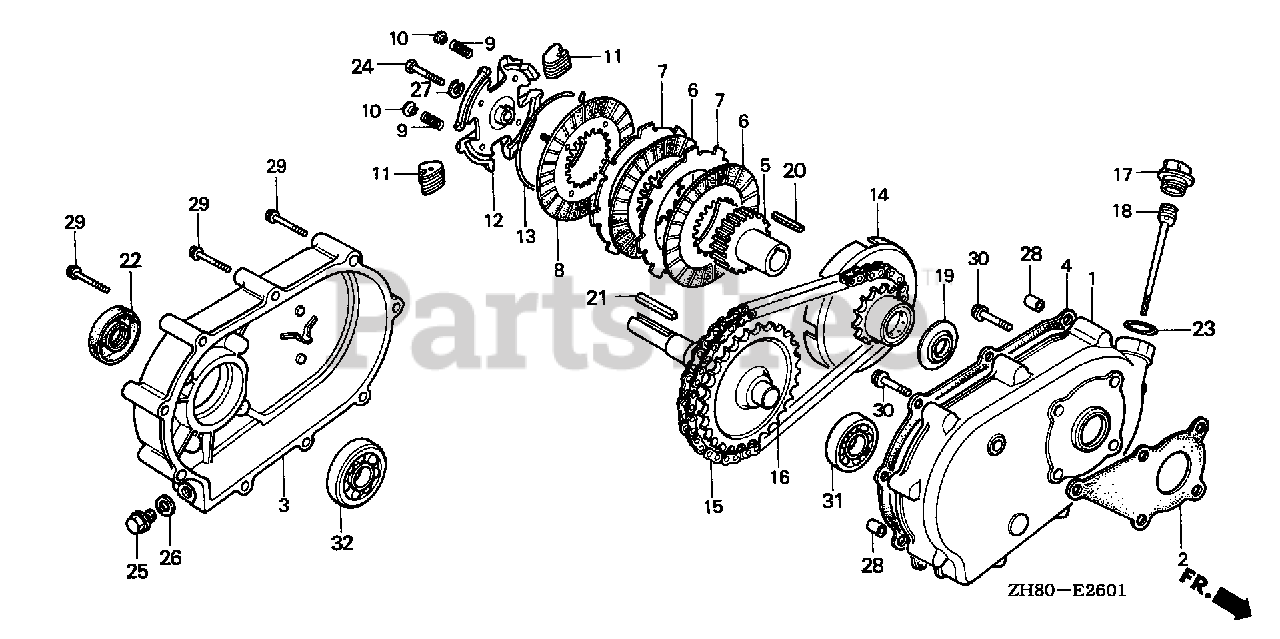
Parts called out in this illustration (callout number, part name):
1	CASE, REDUCTION
2	GASKET, REDUCTION CASE
3	COVER, REDUCTION
4	GASKET, REDUCTION COVER
5	CENTER, CLUTCH
6	DISK, CLUTCH FRICTION
7	PLATE, CLUTCH
8	PLATE, CLUTCH PRESSURE
9	SPRING, CLUTCH FREE
10	HOLDER, CLUTCH SPRING
11	WEIGHT, CLUTCH
12	HOLDER, CLUTCH WEIGHT
13	CENTER, CLUTCH WEIGHT
14	SPROCKET, DRIVE
15	CHAIN, DRIVE (RK428SH-36LE)
16	SHAFT, P.T.O. (28T)
17	CAP, REDUCTION OIL (BLACK)
17	CAP, REDUCTION OIL (GRAY)
18	DIPSTICK, OIL
19	WASHER, THRUST (20MM)
21	KEY (7X7X33) (OVER SIZE) (YELLOW)
22	OIL SEAL (30X50X7)
22	OIL SEAL (PJ30507)
23	O-RING (26X2.7)
24	BOLT, HEX. (8X35)
25	BOLT, DRAIN PLUG (12MM)
26	WASHER, DRAIN PLUG (12MM)
27	WASHER, SPRING (8MM)
28	PIN, DOWEL (8X10)
29	BOLT, FLANGE (6X55)
30	BOLT, FLANGE (8X22)
31	BEARING, RADIAL BALL (6205)
32	BEARING, RADIAL BALL (6206)
